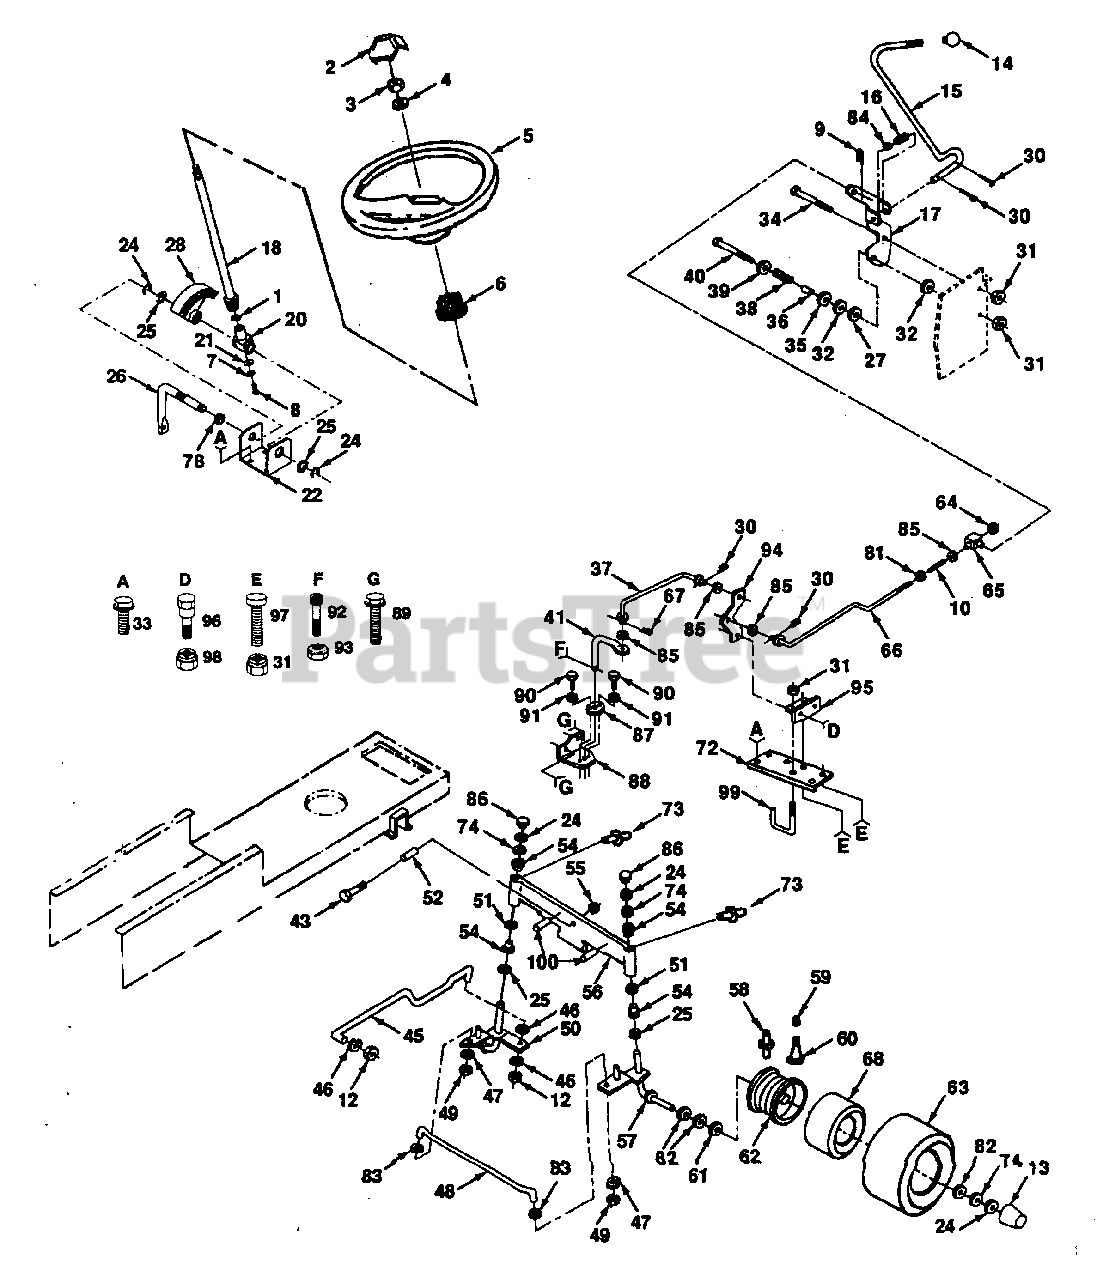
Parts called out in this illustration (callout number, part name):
2	Insert, Steering Wheel
3	Nut, Toplock, Jam 1/2-20
5	Wheel, Steering
6	Adapter, Steering Wheel
7	Washer, Lock 1/4
8	Screw, Hex, Socket 1/4-20 x 5/8
9	Spring, Retainer
10	Spring, Compression
12	Nut, Hex, Fin 3/8-24 UNF
14	Knob, Gearshift
16	Spring, Torsion
17	Bracket, Control Rod
18	Shaft, Steering
20	Support, Shaft
21	Washer, Shim 1/4 x 5/8 x .062
22	Bracket, Steering
25	Bearing, Thrust
26	Shaft, Pitman
27	Washer, Phenolic
28	Gear, Sector
30	Pin, Cotter 1/8 x 3/4
31	Nut, Crownlock 3/8-16
32	Washer, Friction
33	Screw, Hex, Washer Thrdrol. 3/8-16 x 3/4
34	Bolt, Hex, Shoulder 3/8-16 x 1-3/8
35	Washer 21/32 x 1-1/4 x 16 Gauge
37	Link, Control, Pump
38	Spring, Compression
39	Washer 13/32 x 1-1/4 x 12 Gauge
40	Bolt, Hex 3/8-16 x 3
41	Lever, Pump Control
43	Bolt, Hex 5/8-11 x 3-1/2
46	Washer, Lock 3/8
47	Washer, Lock 5/16
48	Rod, Tie
49	Nut, Hex 5/16-24 UNF
50	Spindle, L.H.
51	Washer 27/32 x 1-1/4 x 16 Gauge
52	Spacer, Bearing
54	Bearing
55	Locknut, Flange 5/8-11
57	Spindle, R.H.
58	Fitting, Grease
61	Bearing
62	Rim, Front
63	Tire, Front
64	Locknut, Hex w/Washer Insert 3/8-16 UNC
66	Rod, Control, Adjustable
67	Clip, Hairpin
68	Tube (Optional, Service Part)
72	Bracket, Chassis, Reinforcement, Hydro
73	Fitting, Grease
74	Washer 25/32 x 1-5/8 x 16 Gauge
78	Nyliner, Snap In
81	Washer 13/32 x 3/4 x 12 Gauge
82	Washer 25/32 x 1-1/4 x 16 Gauge
83	Washer 11/32 x 3/4 x 16 Gauge
84	Washer 15/32 x 15/16 x 16 Gauge
85	Washer, Spring
87	Guide, Control
88	Bracket Control Guide
89	Screw, Hex, Washer Thrdrol. 5/16-18 x 3/4 Type TT
90	Screw, Hex Tap #10-24 UNC x .625
91	Washer 7/32 x 1/2 x 16 Gauge
92	Screw, Hex, Socket Head #10-24 UNC
93	Locknut #10-24 UNC
95	Bracket, Bellcrank Pivot
96	Bolt, Shoulder
97	Bolt, Hex, Fin 3/8-16 UNC x 1
98	Nut, Crownlock 3/8-16 UNC x 1
99	Keeper, Centerspan
